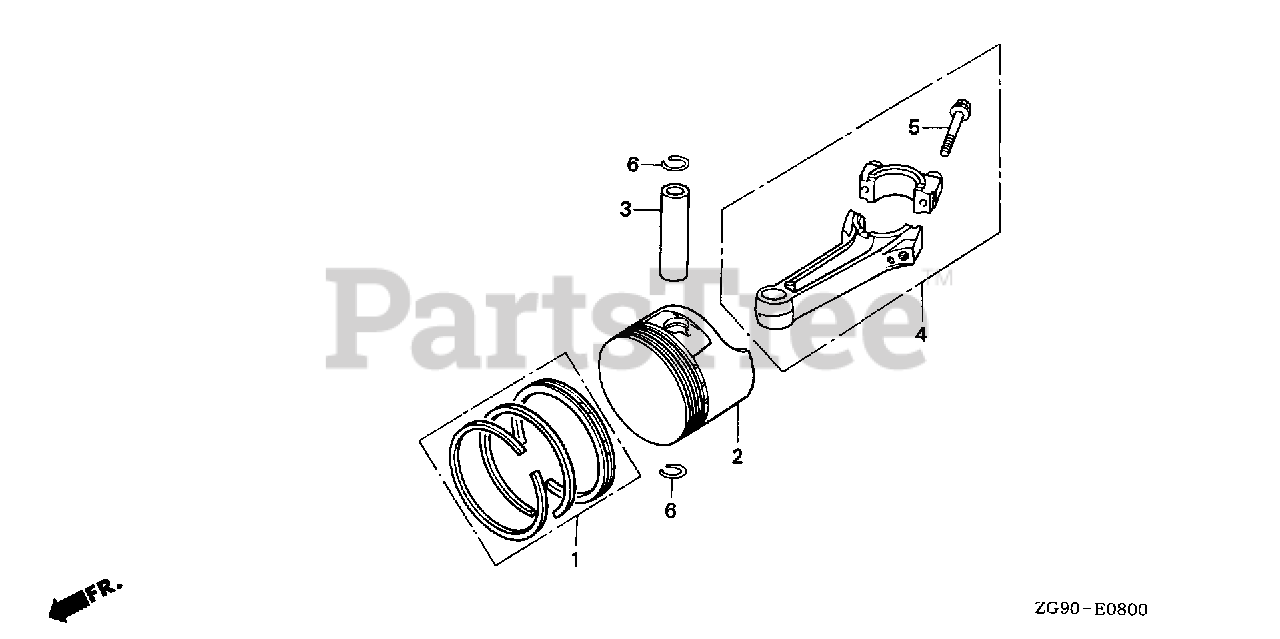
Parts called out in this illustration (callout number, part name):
1	RING SET, PISTON (STD) (GOETZE)
1	RING SET, PISTON (STD) (FEDERAL MOGUL)
1	RING SET, PISTON (STD) (TEIKOKU)
1	RING SET, PISTON (0.25)
1	RING SET, PISTON (0.25) (TEIKOKU)
1	RING SET, PISTON (0.50)
1	RING SET, PISTON (0.75) (GOETZE)
1	RING SET, PISTON (0.75)
1	RING SET, PISTON (0.75) (TEIKOKU)
2	PISTON (STD)
2	PISTON (0.25)
2	PISTON (0.50)
2	PISTON (0.75)
3	PIN, PISTON
4	ROD ASSY., CONNECTING
5	BOLT, CONNECTING ROD
6	CLIP, PISTON PIN (13MM)
